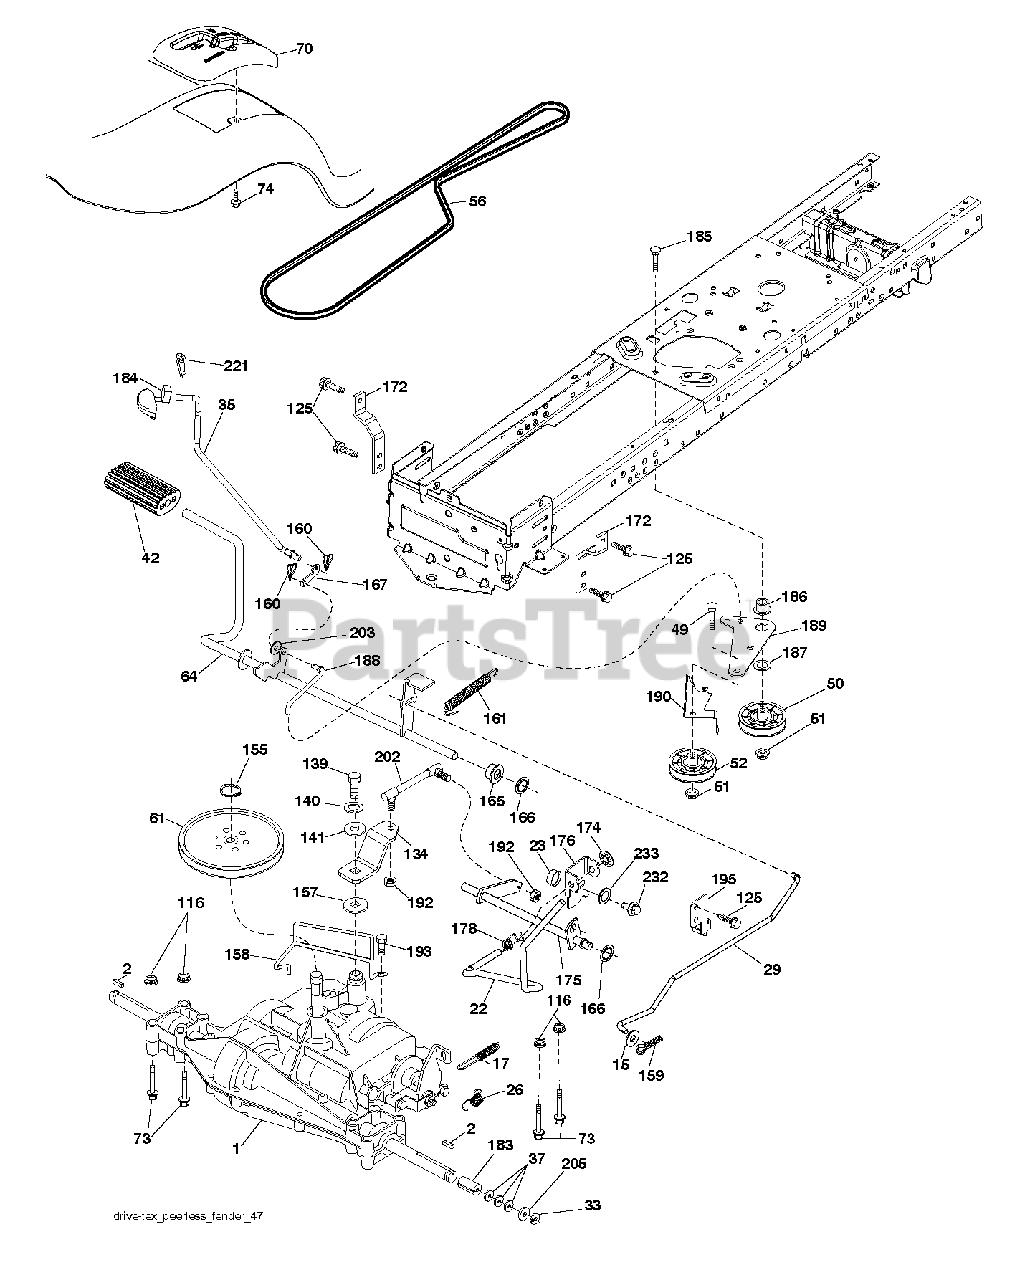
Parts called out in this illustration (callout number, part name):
2	SQUARE KEY
15	WASHER
33	E-RING LT
50	IDLER.FLAT.910.OFFSET
52	IDLER.V-GROOVE.910.OFFSET
74	SCREW.HI-LO.CONSOLE
116	NUT LOCK HEX FLANGE 5/16-18
159	COTTER PIN
160	RETAINER CLIP
161	SPRING, RETURN LT
166	NUT.PUSH.625
167	LATCH.BRAKE.SPRING
183	SPACER AXLE
186	SPACER.RETAINER
188	LINK.CLUTCH.GROUND.DRIVE
189	BELLCRANK.GROUND.DRIVE.TEX.
190	KEEPER.BELLCRANK.DRIVE
221	RETAINER.SPRING.CLIP.H
